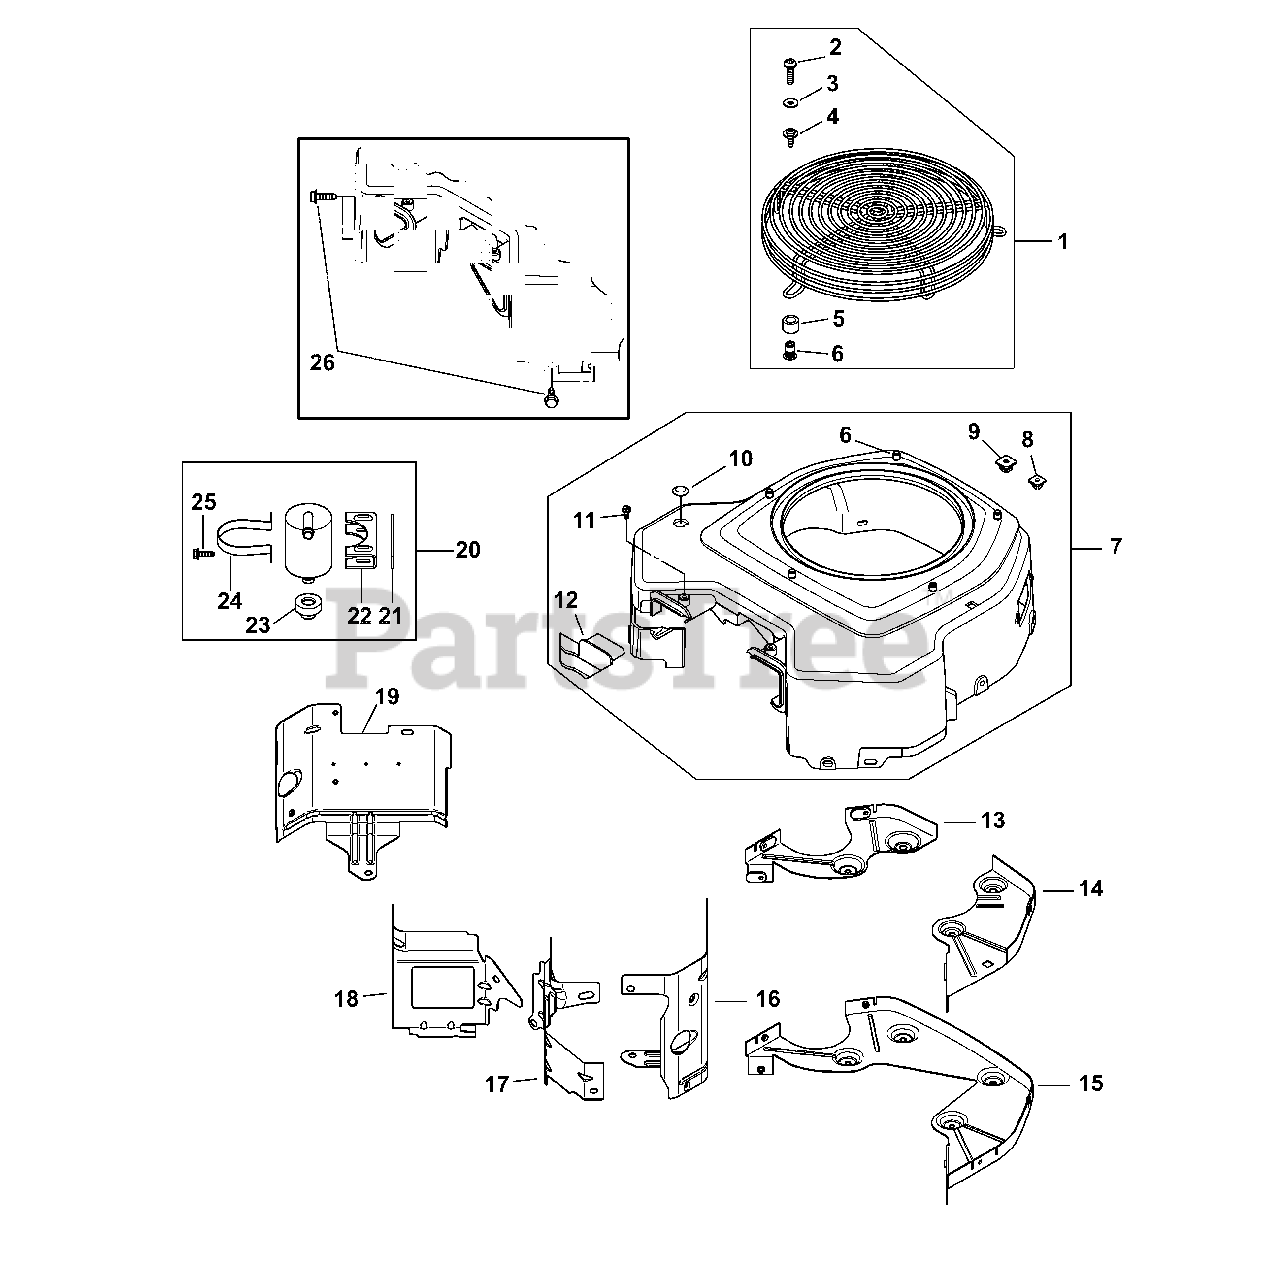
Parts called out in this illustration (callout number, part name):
1	Guard Kit (Inc. 2-4 & KH-24-445-01-S)
2	Pan Screw, M5 x 0.8 x 15
3	Flat Washer, 7/32
5	Threaded Insert
6	Spacer
7	Blower Housing Assembly Kit
10	Button Plug, 9/16
11	Tap Screw, #8-18 x 1/2
12	Blower Housing Cover
13	#1 Side Backing Plate
14	#2 Side Backing Plate
15	Backing Plate Kit (Inc. KH-M-561016-S)
16	Cylinder Baffle Kit, #2 Side
17	Valley Baffle, #2 Side
18	Valley Baffle, #1 Side
19	Cylinder Barrel Kit, #1 Side
20	Breather Separator Kit
22	Breather Separator Bracket
23	Rubber Grommet
24	Breather Strap
25	Flange Screw, M5 x 0.8 x 16
26	Flange Screw, M6 x 1.0 x 16
